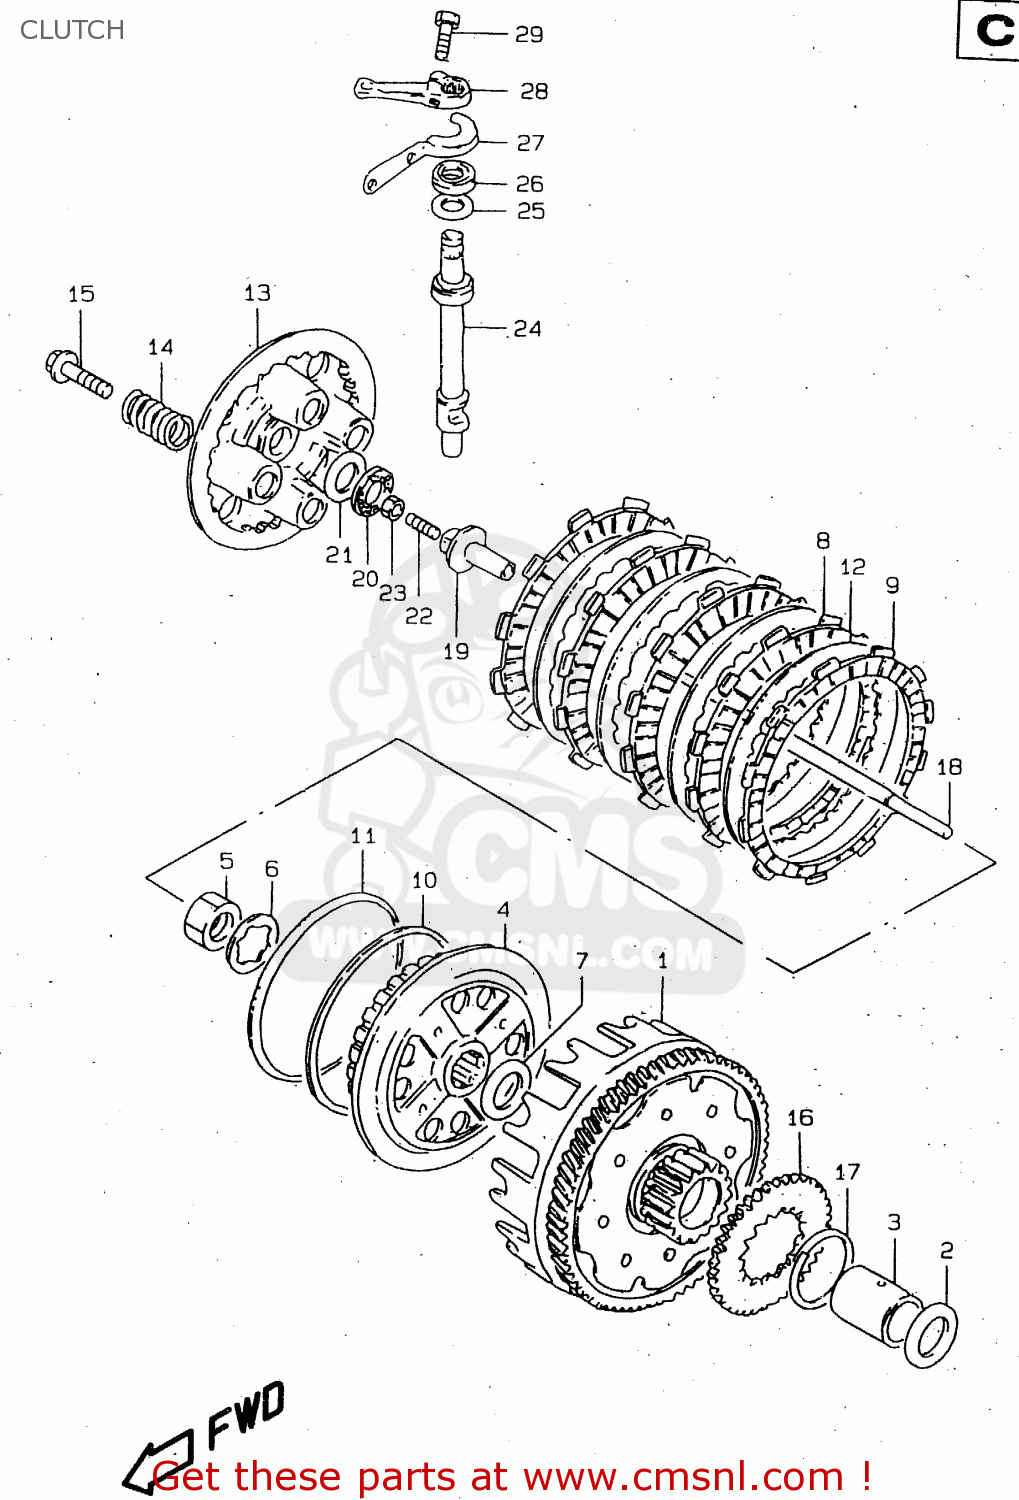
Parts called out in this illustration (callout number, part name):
1	GEAR ASSY,PRI DRIVEN
2	WASHER
3	SPACER(22X28X37.5)
4	HUB,CLUTCH SLEEVE
5	NUT
6	WASHER,LOCK
7	WASHER
8	PLATE,CLUTCH DRIVE (NAS)
9	PLATE,CLUTCH DRIVE(T:3.5) (NAS)
10	SEAT,WAVE WASHER(T:1.4)
11	WASHER
12	PLATE,CLUTCH DRIVEN(T:1.6) (NAS)
13	DISC,CLUTCH PRESSURE
14	SPRING
15	BOLT(6X16)
16	GEAR,OIL PUMP DRIVE
17	CIRCLIP
18	ROD,CLUTCH PUSH
19	PIECE,CLUTCH PUSH
20	BEARING(15X28X2)
21	WASHER(15.5X28X1)
22	SCREW(6X25)
23	NUT
24	CAMSHAFT,CLUTCH RELEASE
25	WASHER(14.5X22X1)
26	OIL SEAL
27	PLATE,CLUTCH RRS CAMSHAFT SEAL
28	ARM,CLUTCH RELEASE
29	BOLT
